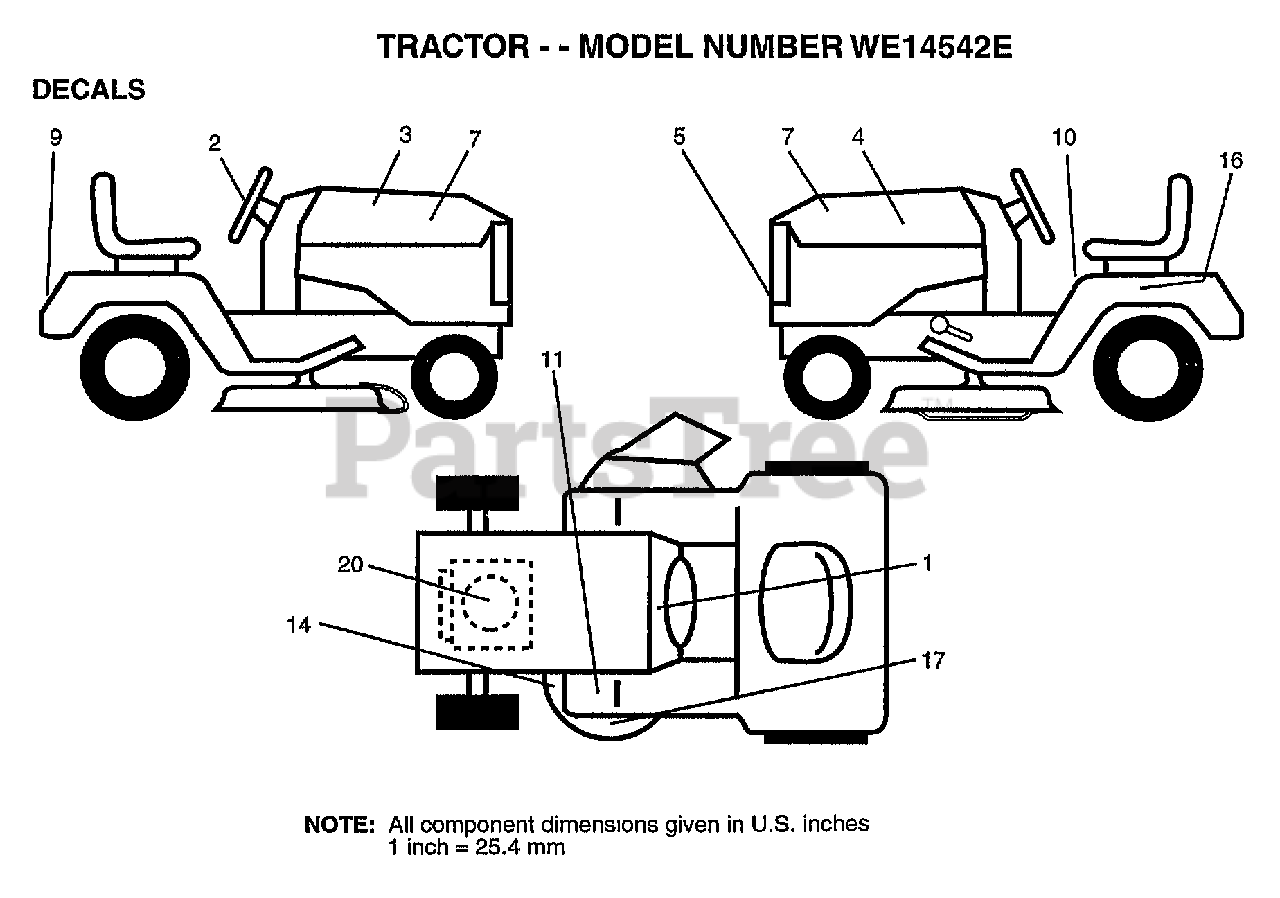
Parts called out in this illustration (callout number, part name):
1	"DECAL DASH,OPER."
2	"DECAL INS,STRG WH"
3	"DECAL HOOD,RH"
4	DECAL HOOD LH
5	"DECAL GRILLE,LENS"
7	"DECAL PANEL,SIDE"
9	DECAL-FENDER
10	"DECAL DANGER,FEND"
14	"DECAL-SCHEM,BELT"
16	DECAL.BATRY.3-3908
20	DECAL, ENGINE
